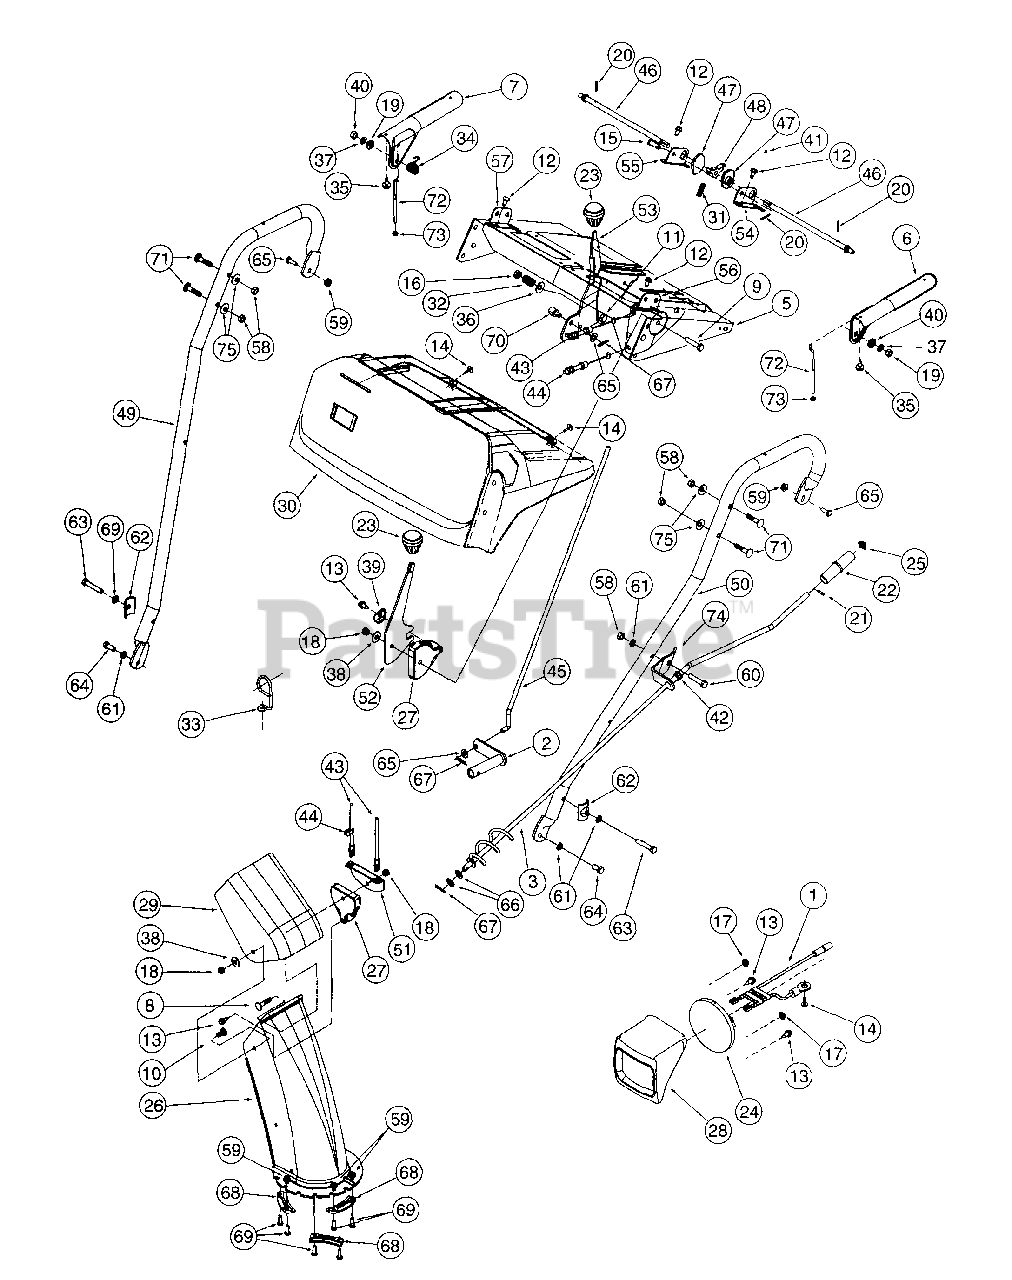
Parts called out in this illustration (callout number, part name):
1	Harness for Headlight
2	Shift Arm Assembly
3	Chute Crank Assembly
6	Handle Assembly Engagement (L.H.)
7	Handle Assembly Engagement (R.H.)
8	Carriage Bolt 5/16-18 x 1.50
9	Hex Bolt 5/16-18 x 1.5
10	Carriage Bolt 5/16-18 x.75
11	Hex Screw 3/8-24 x 1.5
12	Hex Washer Hd. TT Screw 1/4-20 x 0.5"
13	Hex AB Tap Screw 1/4 x .62
14	Hex B-Tapp Screw # 10-16 x.62
15	Clevis Pin
16	Hex lns. Lock Nut 3/8-24
17	Self Threading Nut
18	Lock Nut 5/16-18
19	Hex Nut
20	Cotter Pin
21	Roll Pin
22	Chute Crank Knob
23	Shift Knob
24	Headlight
25	Push Cap
26	Lower Chute
27	Cable Guide
28	Headlight Bezel
29	Upper Chute
30	Handle Panel
31	Compression Spring
32	Compression Spring
33	Cable Control Wire
34	Torsion Spring
35	Rubber Bumper
36	Bell Washer .380 x .880 x .062
37	Lock Washer 5/16 I.D.
38	Washer 5/6 I.D.
39	Special Washer
40	Special Washer
41	Grease
42	Plastic Bushing
43	Chute Deflector Control Cable
44	Chute Deflector Cable w/ Clip
45	Shift Rod
46	Cam Rod
47	Cam Handle Lock
48	Pawl Handle lock
58	Hex Nut 5/16-18 Thd.
59	Hex Flange Locked Nut 1/4-20 Thd.
60	Hex Bolt 5/16-18 x 1.5
61	Lock Washer 5/16
62	Handle Tab
63	Hex Bolt 5/16-18 x 1.75 Gr.5
64	Hex Bolt
65	Flat Washer 5/16
66	Flat Washer 3/8 x .738 x .063
67	Hairpin Clip
68	Chute Flange Keeper
69	Hex Bolt 5/16-18 x 1.50
70	Ferrule
71	Carriage Bolt 5/16-18 x 1.50
72	Z Fitting
73	Hex Nut # 10-24
